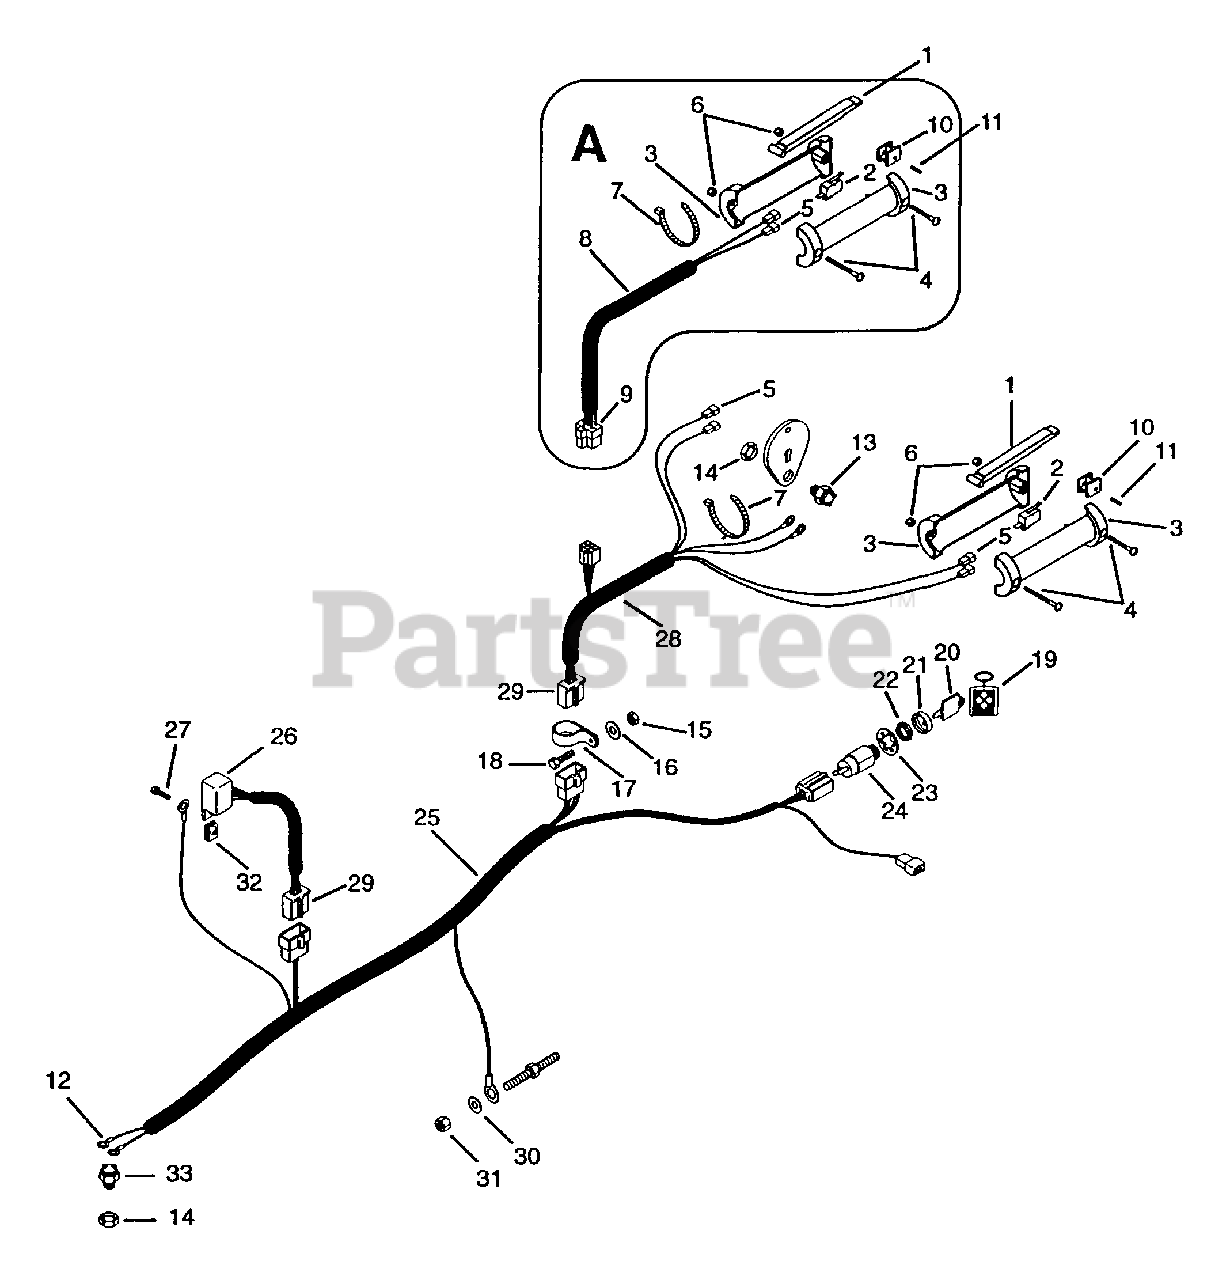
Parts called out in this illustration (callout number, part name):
1	Lever
2	Switch
3	Handle, Left Hand & Right Hand
4	Screw-Machine 10-24 x 1.50
5	Terminal, Female
6	Nut-Locking 10-24
7	Tie Wrap, Black
8	Harness, Steering Brake
9	Connector
10	Holder, Switch
11	Pin-Roll .094 x .750
12	Terminal, Eyelet
13	Switch, Interlock Closed
14	Nut-Stamped .56-18
15	Nut-Locking-Nylon .250-20 Grade 2
16	Washer-Flat-Steel .281 x .620 x .065
17	Cable Clamp
18	Bolt-Hex .25-20 x .75 Grade 5
19	Key Chain
20	lgnition Switch Key
21	Cap-Ignition Switch
22	Nut-Panel.625-32
23	Washer-Lock Internal .625 x .045
24	Switch Assembly
25	Harness, 8 & 12-HP Recoil
26	Module
27	Bolt-Hex .25-20 x .63
28	Harness, Wiring Handlebar
29	Terminal
30	Washer-Flat-Steel .459 x .938 x .065
31	Nut-Locking-Nylon .375-16 Grade 2
32	Nut-Speed .25-20
33	Switch, Interlock Open
